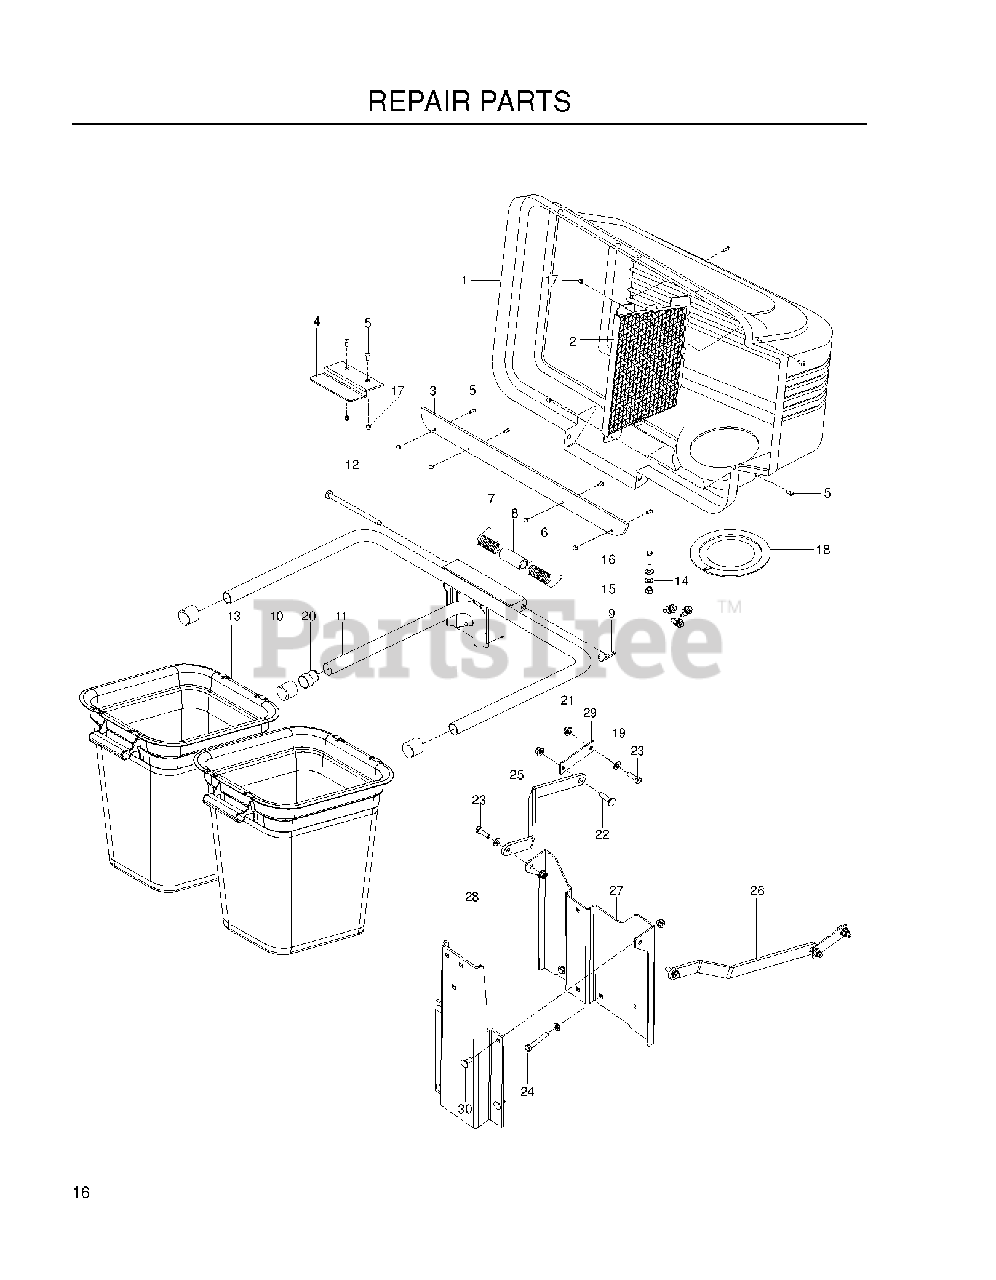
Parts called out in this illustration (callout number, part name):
1	HOOD ASM
2	COVER SCREEN
3	STRIP.REINFORCE.BAGGER.2BIN.BL
4	LATCH CER38
5	SCREW #10-24 X 5/8
6	SPRING COVER LH
7	SPRING COVER RH
8	SPACER.COVER.BAGGER
9	RETAINER SPRING
10	TUBING PLUG
11	FRAME.ASM.BAGGER.2BIN.QC42B
12	BAGGER.HINGE.PIN
13	CONTAINER BAG, SOFT
14	WASHER #10
15	NUT 10-24 NYLOC
16	SCREW 10-24 X 3/4
17	NUT 10-24 ACORN ZD
18	GASKET.COVER.BAGGER
19	FLAT WASHER 5/16 SAE
20	SPACER PLUG, BAGGER
21	5/16-18 NYLOC FLANGE NUT
22	BOLT, CARRIAGE 5/16X1-1/4
23	HCS 5/16C X 1
24	HCS 5/16-18X2
25	STRAP, SUPPORT, RT BLK
26	STRAP, SUPPORT, LT BLK
27	MOUNT, 2 BIN COLLECT, BLK
28	BRACKET, COLLECTION BLK
29	REINFORCEMENT PLATE BLK
30	BOLT 5/16C X 3/4" CARRIAGE
